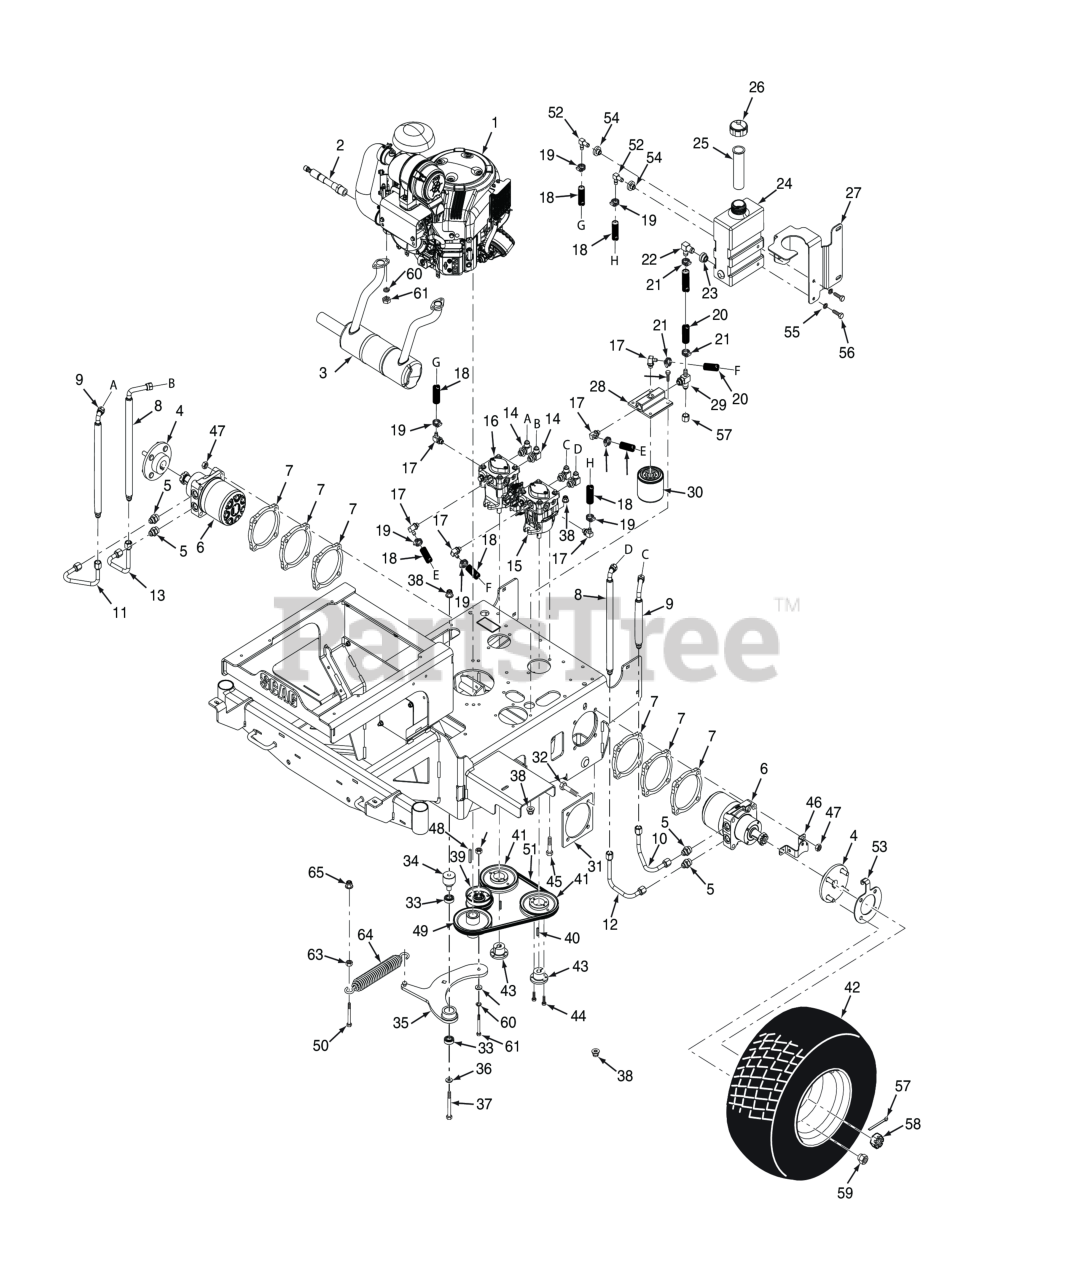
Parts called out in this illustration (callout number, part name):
1	Engine, 21 HP Briggs Vanguard
2	Hose, Oil Drain, Kohler - ECV860
3	Muffler, 21 HP BV
4	Wheel Hub Assy., SVRII
5	TUBE UNION, 3/4-16 JIC TO 7/8-14 "O" RING
6	Wheel Motor, Parker
7	Spacer, Wheel Motor
8	Hose Assy, 17.50"
9	Hose Assy, 16.25
10	Tube Assy, 1/2" LH Upper
11	Tube Assy, 1/2" RH Upper
12	Tube Assy, 1/2" LH Lower
13	Tube Assy, 1/2" RH Lower
14	Elbow, 90 Degree 3/4-16 JIC x 3/4-16 O-Ring
15	Pump, LH
16	Pump, RH
17	Elbow, 90 Degree - 9/16" O-Ring x 3/8" Hose
18	Hose, 3/8" ID - 10-1/4" Long (Order By The Inch)
19	Clamp, .69" Max. / .25" Min. Dia.
20	Hose Assembly, 1/2" ID (Oil Reservoir to Filter Base)
21	Clamp, Cable 3/4" I.D.
22	Fitting, 90 Degree - 1/2" Hose
23	Bushing, 0.78" Dia. Viton
24	Hyd. Tank Assy
25	Insert, Filler Neck
26	CAP, HYDRAULIC TANK
27	Mounting Bracket, Oil Reservoir
28	Filter Head Assembly
29	Tee, 3/8" O-Ring x JIC x 1/2" Hose
30	OIL FILTER, SPECIAL
31	Plate Weldment, Motor Backing
32	Bolt, Hex Head 1/2-13 x 4-1/4"
33	BEARINGS, BALL, NEUTRAL RETURN
34	Pivot, Idler
35	Idler Arm Assembly
36	Flatwasher, 3/8 (.391 x .938 x .105 HD) Grade 8
37	Bolt, Hex Head 3/8- 16 x 3.50 - Stainless Steel
38	Nut, Flange Elastic Stop 3/8 - 16 - Stainless Steel
39	Pulley, 3-1/2" Dia.
40	KEY, 5 MM X 5 MM X 25 MM
41	Pulley, 5.45 OD - Tapered Bore"
42	Wheel Assembly, 20 x 12 - 10
43	Hub, Tapered, 15mm Bore
44	Bolt, Hex Head 1/4-20 x 1" Grade 8 Black
45	Bolt, Hex Head 3/8 - 16 x 1.50 - Stainless Steel
46	Plate, Speed Sensor
47	Locknut, Hex 1/2-13 Center Lock
48	Key, 1/4 x 1/4 x 2.0"
49	Pulley 5.45 OD x 1.125 Bore
50	Bolt, Hex Head 3/8-16 x 2-1/4" - Stainless Steel
51	Belt, Pump Drive
52	Elbow, 90 Degree, 9/16-18 JIC x 9/16 O-Ring
53	Plate, Hub Magnet Holder
54	Bushing, 0.56" Dia. Viton
55	Bolt, Hex 5/16 - 18 x .75 - Stainless Steel
56	Washer, Lock 5/16 Spring - Stainless Steel
57	Pin, Cotter 9/16" x 1-1/2"
58	Nut, Hex Castle 1.0-20 UNEF
59	Wheel Nut, 1/2-20 x 13/16
60	Bolt, Hex Head 7/16-20 x 1.25"
61	Flatwasher, 7/16-.469 x 1.750 x 1/4"
62	Flatwasher, 7/16-.469 x 1.75 x .25 (48, 52)
63	Nut, 3/8 - 16 - Stainless Steel
64	Spring, PTO (Gasoline Engines)
65	Nut, Flange Elastic Stop 3/8 - 16 - Stainless Steel
